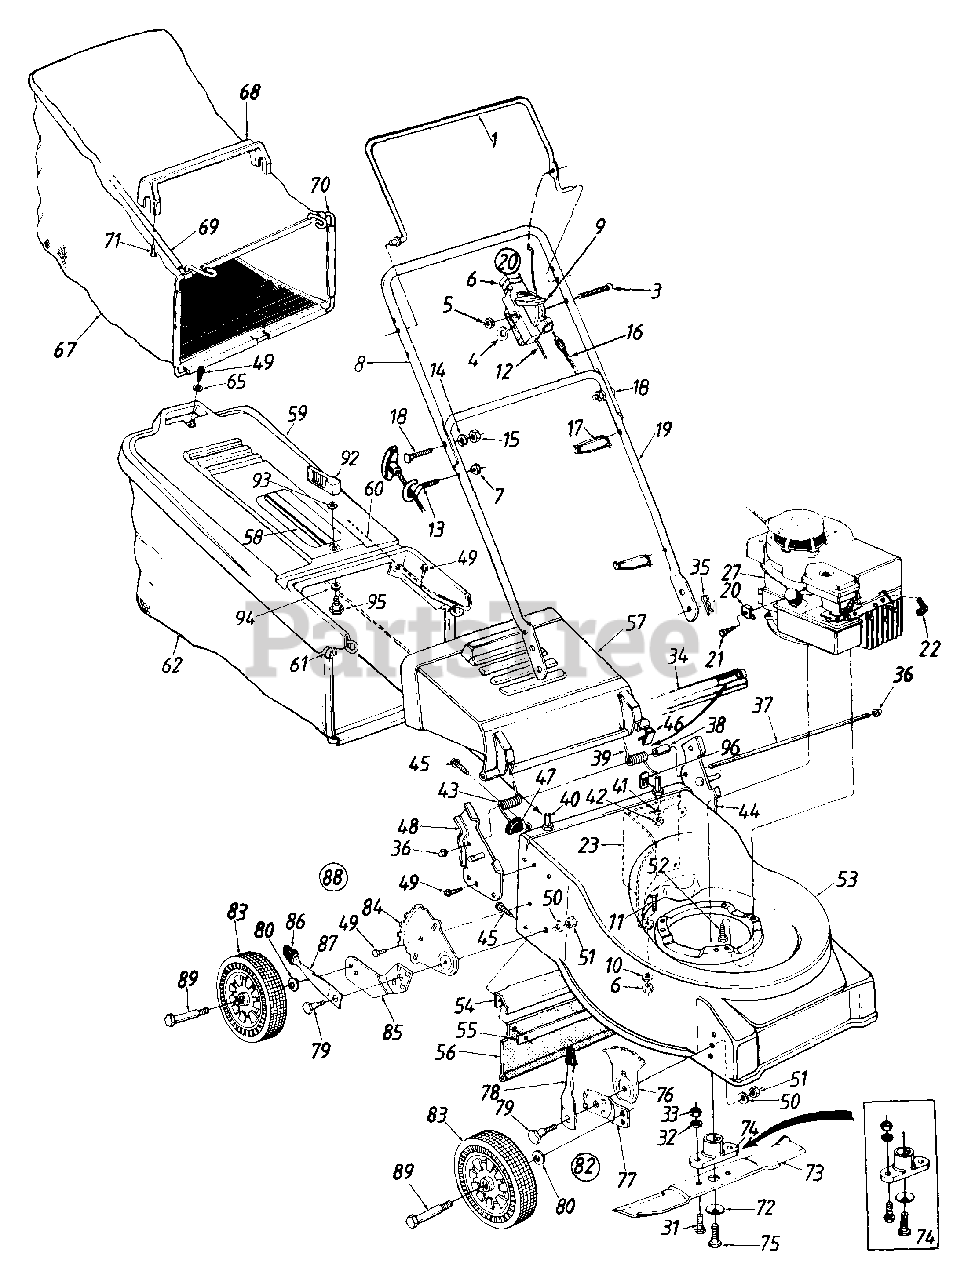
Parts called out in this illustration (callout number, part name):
3	Oval C-Sunk Mach.-Scr.
4	Spr. Wash..66" I.D.
5	Hex L-Nut 1/4-20 Thd.
6	Throttle Body
7	Hex L-Nut 1/4-20 Thd.
10	Bell-Wash. 1/4" I.D.
11	Hex Bolt 1/4-20 x .85"
12	Throttle Control Wire - 45"
13	Rope Guide
14	L-Wash. 5/16" I.D.
15	Hex Nut 5/16-18 Thd.
16	Control Cable - 55"
17	Cable Tie
18	Curved Carriage Bolt 5/16-18 x 1.38" Lg.
19	Lower Handle
20	Throttle Box Comp.
21	Hex Self-Tap Scr. #10-32 x .62" Lg.
22	Spark Plug Boot
31	Hex Bolt 3/8-24 x 1"
32	L-Wash. 3/8" I.D.
33	Hex Nut 3/8-24 Thd.
34	Seal - Extrusion
35	Int. Cotter Pin 5/16" Dia.
36	Cap Speed Nut
37	Hinge Pin 17.75" Lg.
38	Spacer .255" I.D.
39	Torsion Spring - L.H.
40	Shld. Pin 3/8-24 x 1.43" Lg.
41	L-Wash. 3/8" I.D.
42	Hex Jam Nut 3/8-24 Thd.
43	Torsion Spring - R.H.
44	Handle Brkt. Ass'y.- L.H.
45	Torx Mach. AB-Tap Scr. 1/4 x .62" Lg.
46	Deflector Plug
47	Corner Plug
48	Handle Brkt. Ass'y.- R.H.
49	Hex L-Wash. AB-Tap Scr. 1/4 x .62" L.
50	Bell-Wash..39" I.D.
51	Hex Nut 3/8-16 Thd.
52	Hex L-Wash. Hd. Scr. 3/8-16 x 1" Lg.
57	Rear Chute Deflector
58	Hardtop Handle
59	Hardtop Bag Cover
60	Rear Catcher Frame
62	Grass Bag
65	Fl-Wash..281" I.D.
67	Grass Bags
68	Bag Handle
72	Bell-Wash..39" I.D.
73	21" Blade
74	Blade Adapter Kit
75	Hex Bolt 3/8-24 x 1.5" Lg.
76	Height Adj. Plate
78	Spring Lever Ass'y. w/Knob
79	Shld. Bolt .50" Dia. x .357"
80	Bell-Wash..38" I.D. x .88" O.D.
82	Height Adj. Ass'y. Comp.- R.H.
83	Wheel Ass'y. Comp. (Spoked Rim Ass'y.)
84	Index Plate
85	Pivot Bar - R.H.
86	Spring Lever Knob
87	Spring Lever
88	Rear Height Adj. Ass'y. Comp.- R.H.
89	Axle Bolt
92	Grass Catcher Locking Knob
93	Internal L-Wash. 1/4" I.D.
94	Wave Washer 3/8" I.D.
95	Shld. Bolt .342" Dia. x .268"
